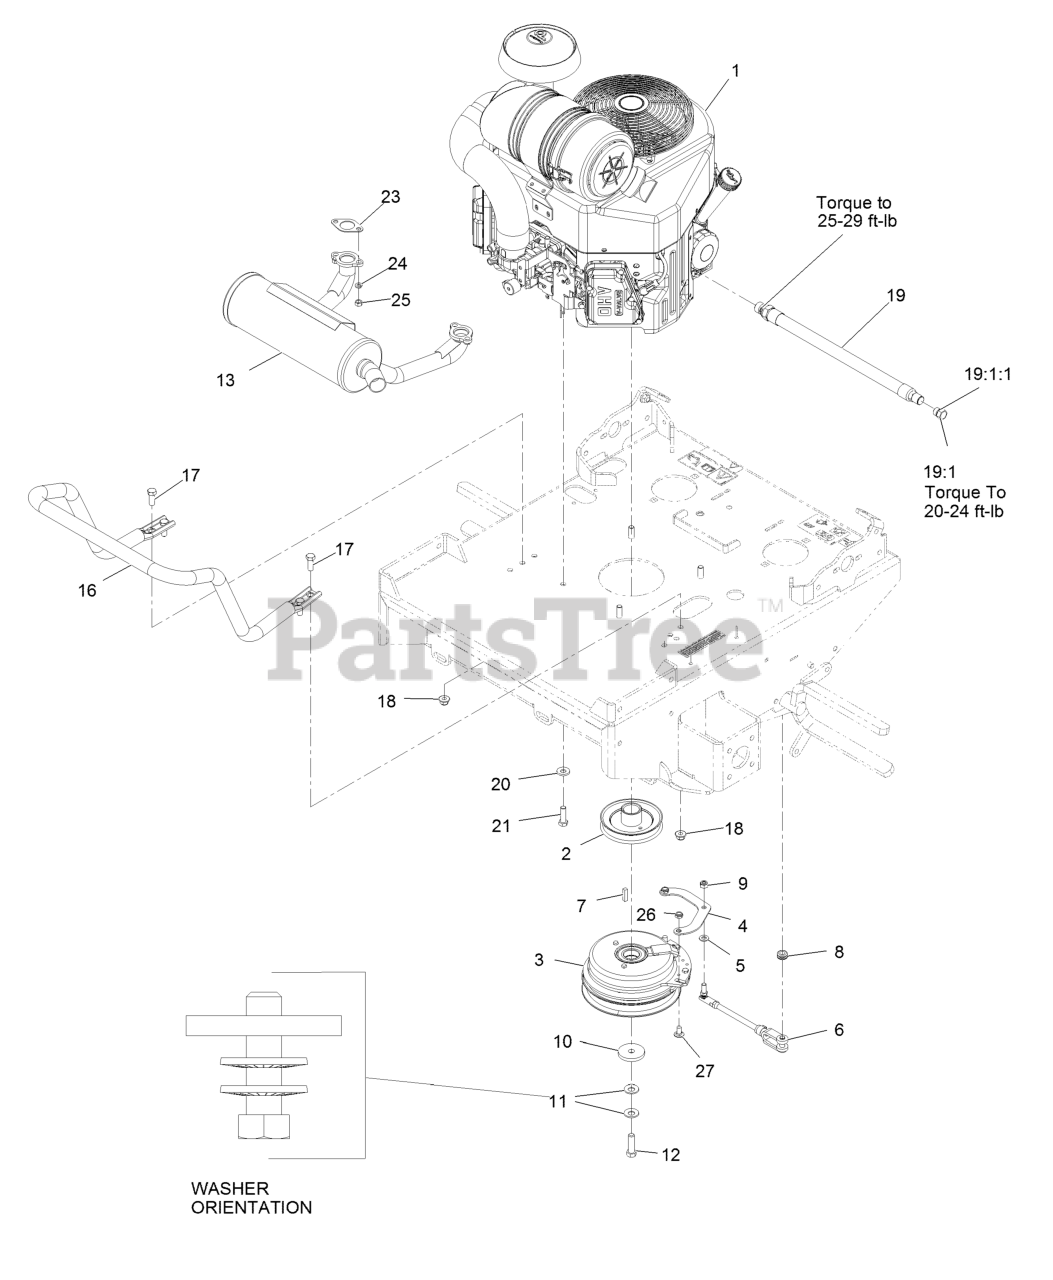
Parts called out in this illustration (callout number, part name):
2	SHEAVE W/ HUB
3	CLUTCH, 200 FT/LBS, 1.13
4	STRAP, CLUTCH
5	WASHER-PLAIN
6	ASM, CLUTCH ANCHOR
7	KEY
8	GROMMET
9	NUT-LOCK
10	WASHER-CLUTCH
11	WASHER-SPRING
12	BOLT-HEX, TAP
13	MUFFLER,HORIZONTAL
16	GUARD-MUFFLER
17	SCREW-HH
18	NUT-HF, NI
19	ASM, ENGINE OIL DRAIN HOS
19:1	PLUG-HH
19:1:1	O-RING
20	WASHER-BELLEVILLE
21	SCREW-HH
23	GASKET-EXHAUST
24	WASHER-LOCK
26	NUT-LOCK, NI
27	SCREW-CARR
